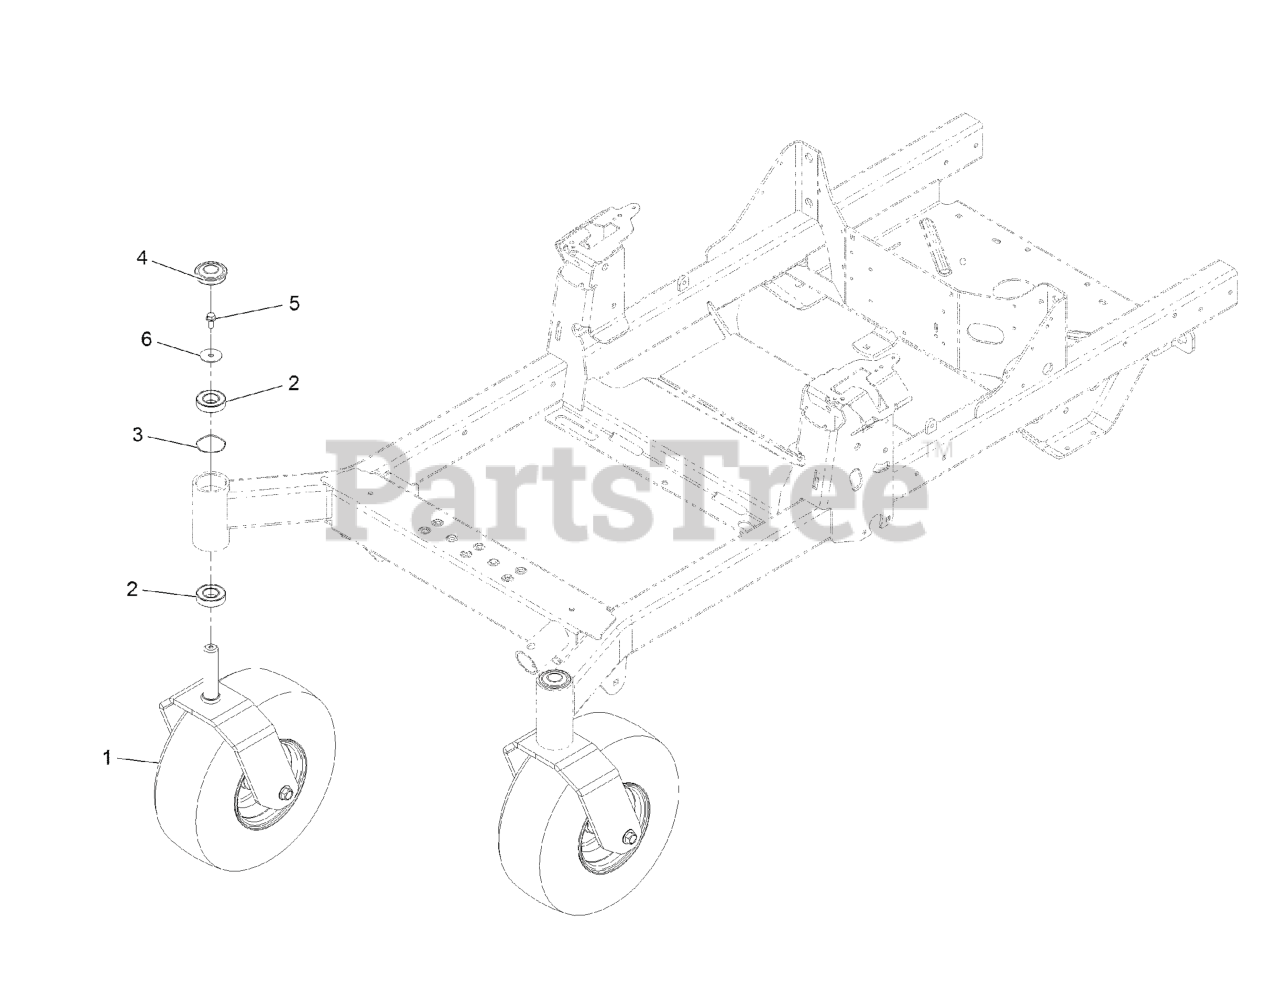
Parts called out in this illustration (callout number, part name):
1	ASM-Front Caster W/Fork
2	BEARING-BALL
4	CAP-GREASE
5	SCREW-HHF
6	WASHER-FLAT
